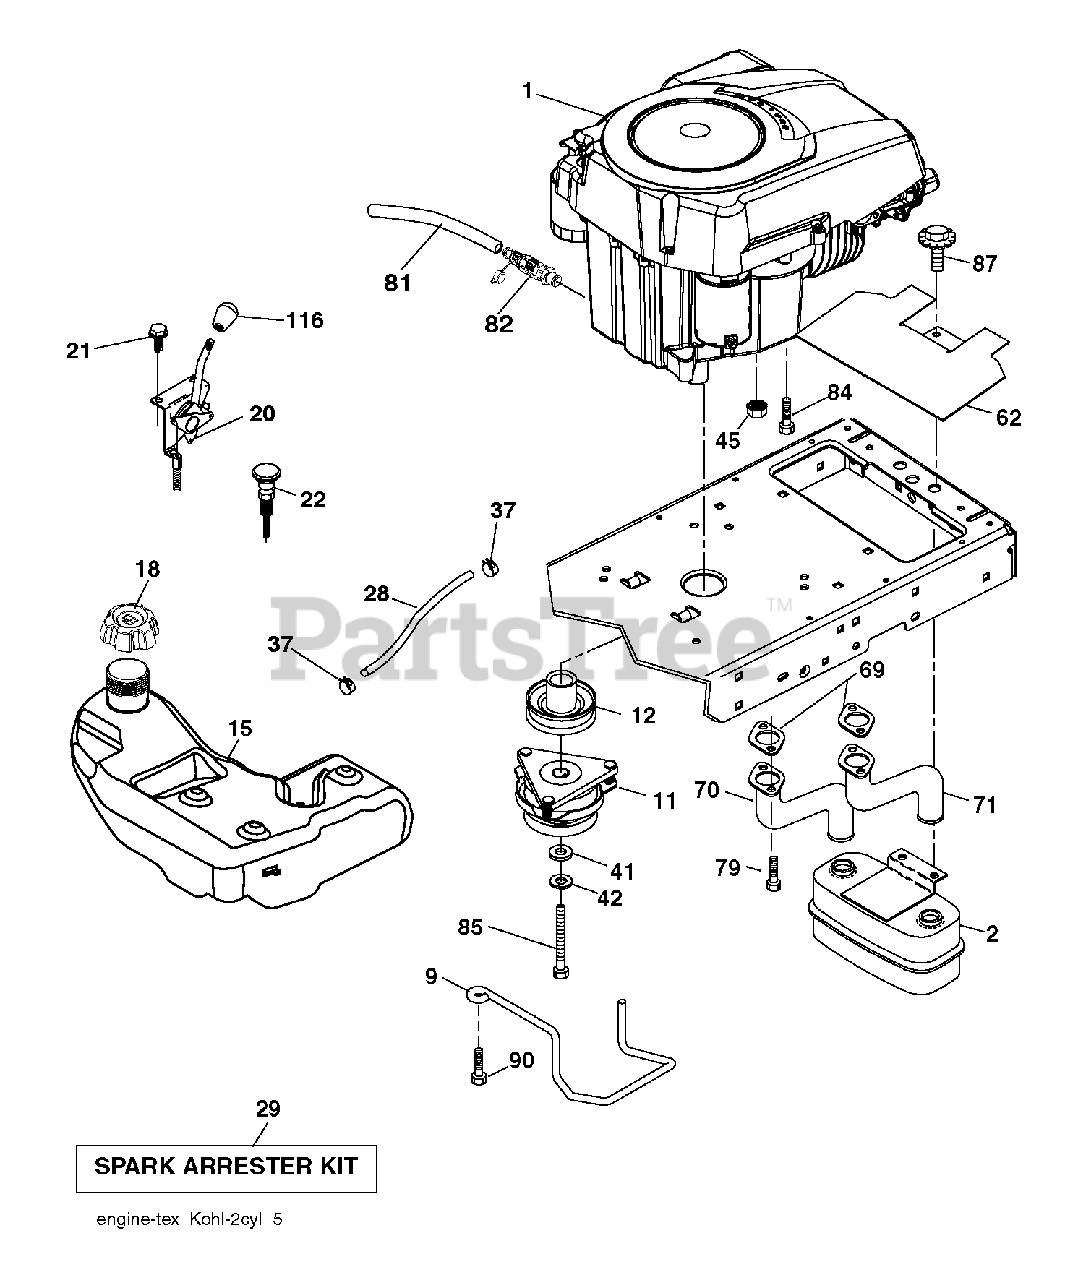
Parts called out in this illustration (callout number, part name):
2	MUFFLER ASSM
9	KEEPER.BELT.ENGINE.4.2
12	PULLEY.ENGINE.TUFFTORQ
18	CAP ASM.FL.RTCHT.3"GRY.E10
20	CONTROL.THROT.PRO
21	SCREW.#10 X 0.750.BOS THREAD
22	CONTROL CHOKE
29	ARRESTER SPARK (OPTIONAL)
37	HOSE CLAMP
42	LOCKWASHER
62	SHIELD.HEAT.MUFFLER
70	PIPE-EXHAUST LH
71	PIPE-EXHAUST RH
79	SCREW.SOCKET HD.5/16-1
81	TUBE, DRAIN OIL ASM.
82	VALUE.OIL.DRAIN
84	SCREW 3/8-16X1
87	BOLT.5/16-18UNCX1.W/SE
90	SCREW 3/8-16X1
116	KNOB - SHIFT
